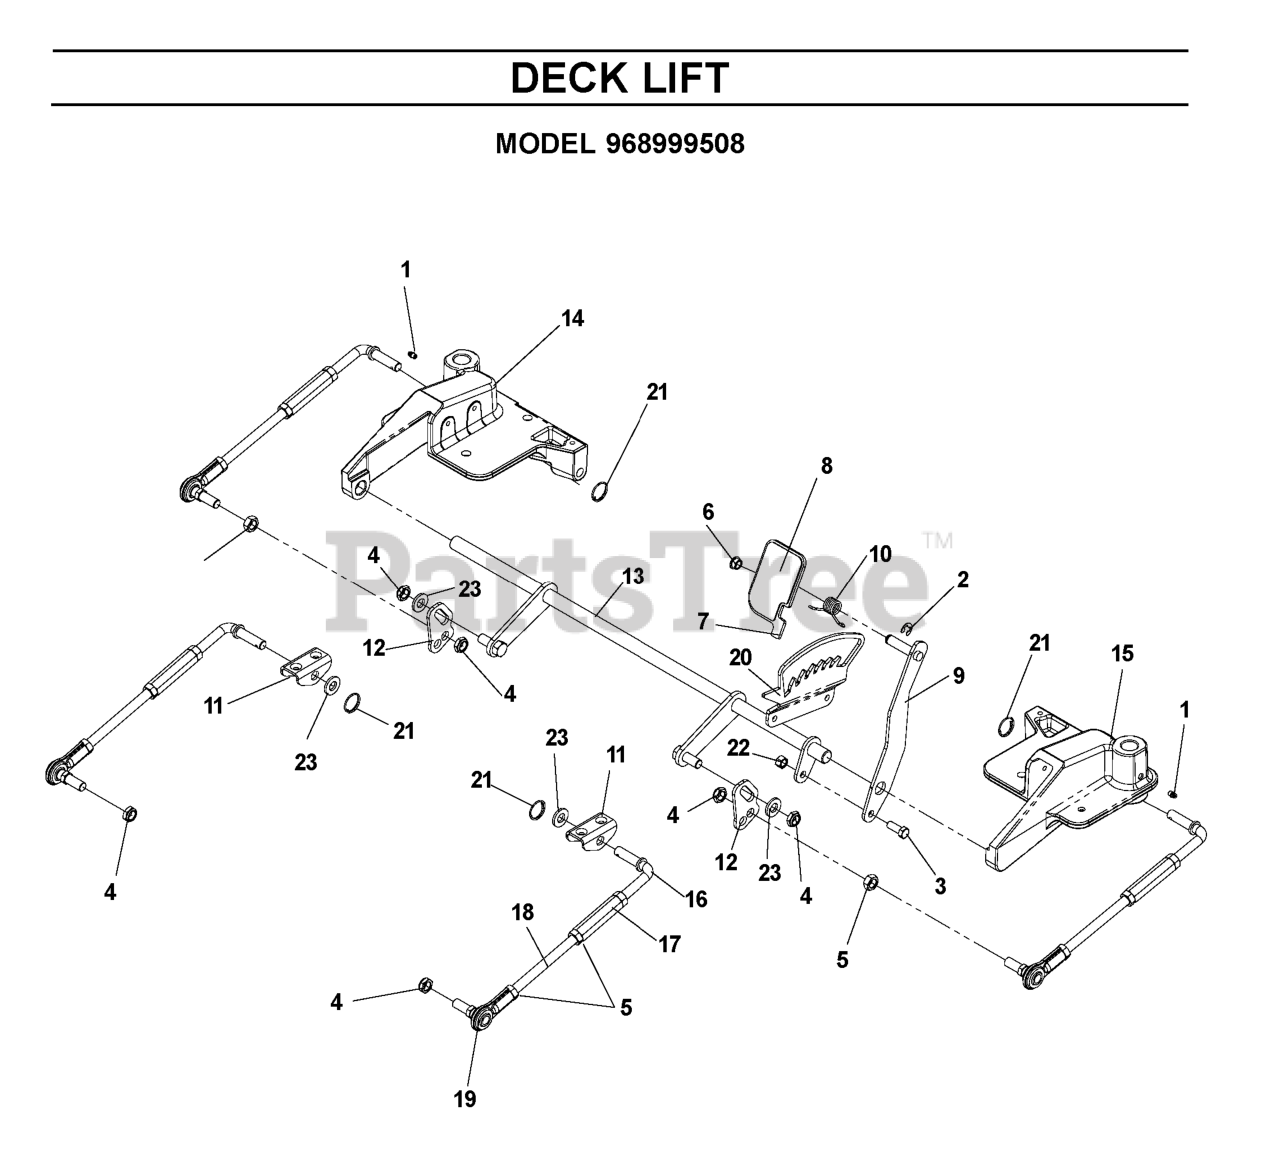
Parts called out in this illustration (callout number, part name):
2	E-RING 1/2 (2 2)
3	HEX BOLT 3/8 X 1"
4	JAM NUT 1/4C (2 2 PW01)
5	NUT 1/2-20 HEX JAM ZD
6	BUSHING, FLANGED NYLON
7	FOOT PEDAL
8	FOOT PAD, NON-SLIP
9	LIFT FOOT, LEVER WELDED
10	SPRING, PEDAL, LIFT
11	BRACKET, DECK HANGER
12	CONNECTOR, DECK LIFT
13	LIFT SHAFT WLDT
14	CASTING, CASTER, LT
15	CASTING, CASTER, RT
17	TURNBUCKLE, 1/2
20	HEIGHT PLATE, DECK
22	NUT 3/8-16 NYLOC
23	WASHER 1/2" FLAT
